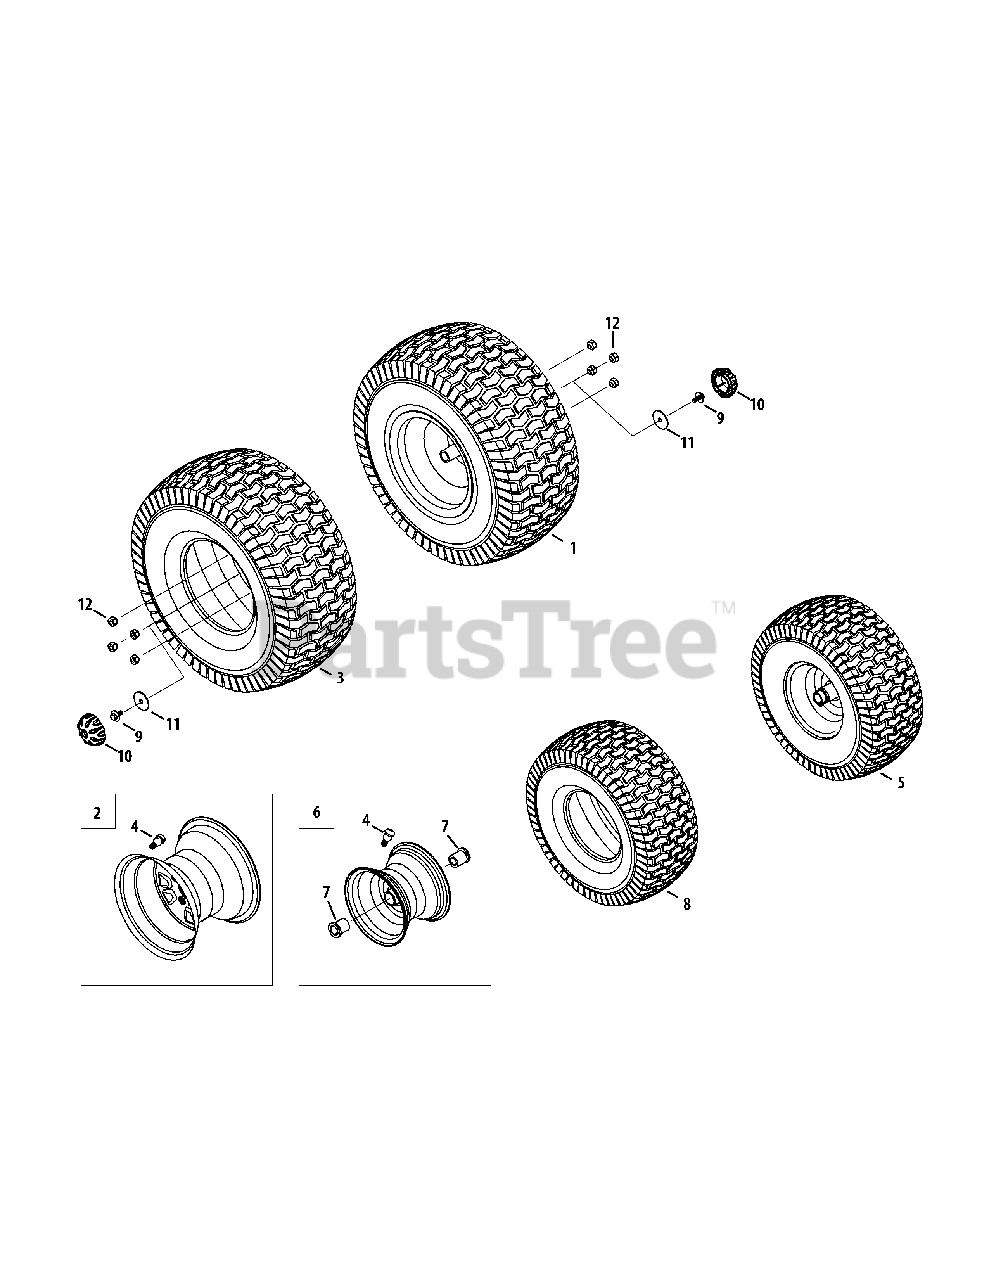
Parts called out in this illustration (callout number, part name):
1	Wheel, Complete, 20 x 8 x 8
2	Rim Ass’y, 8.0 x 7.0 x .750 ID
3	Tire, 20 x 8 x 8 Sq Shoulder
4	Valve, Tubeless Air
5	Wheel, Complete, 15 x 6 x 6
6	Rim Ass’y, 6.0 x 4.5, Flnge Bearings
7	Bearing, Flange, .760 ID
8	Tire, 15 x 6 x 6 Sq Shoulder
9	Screw, 5/16-24 x .850
10	Hub Cap
11	Flat Washer, .350 x 1.59 x .062
12	Lug Nut 7/16-14 (GT)
